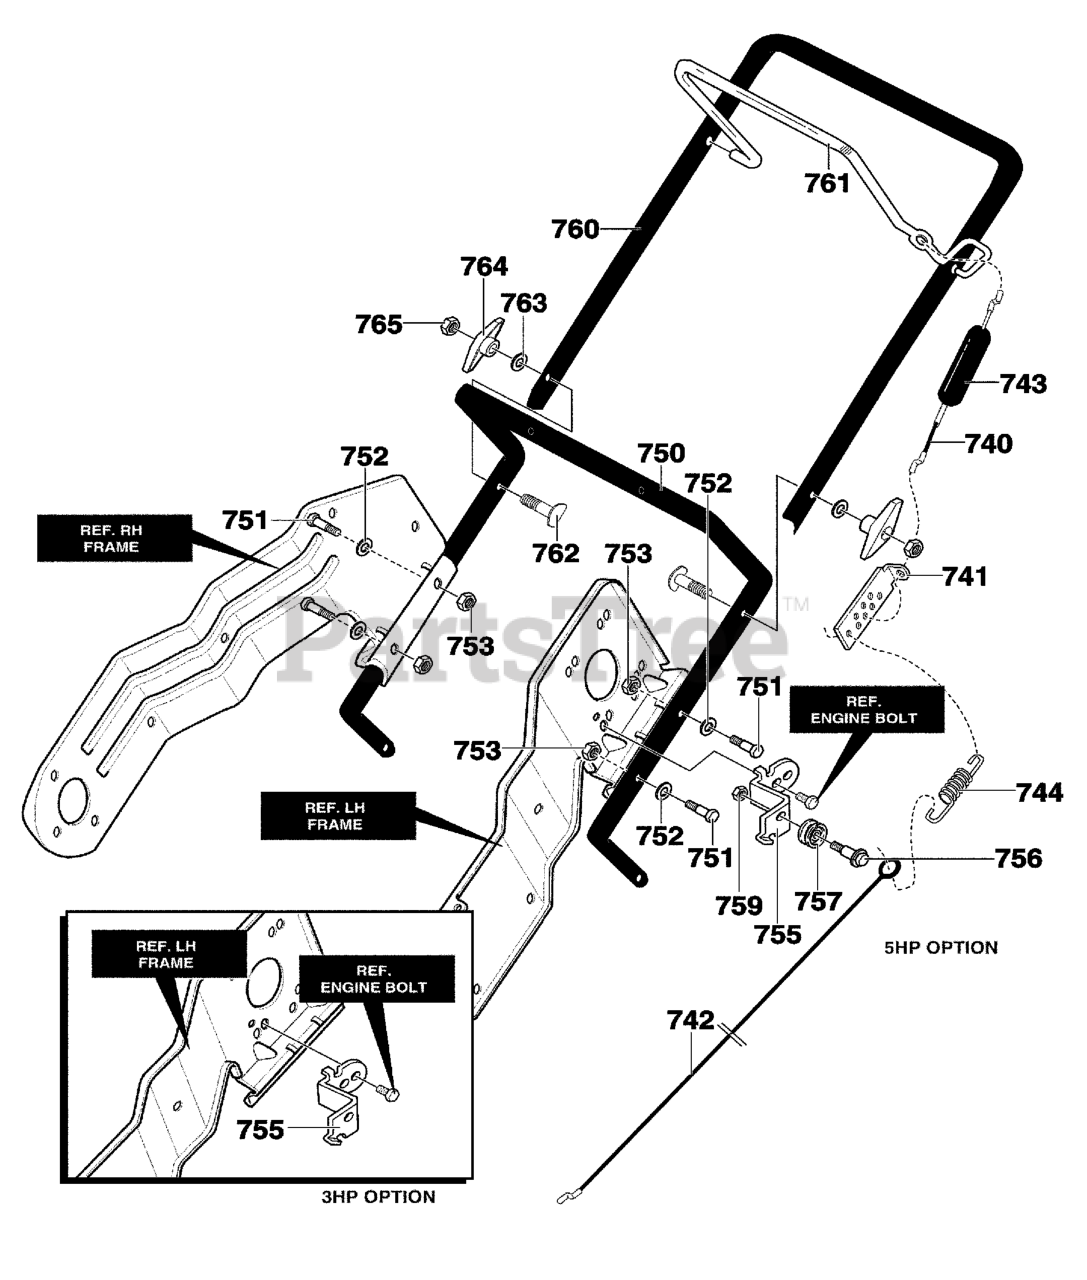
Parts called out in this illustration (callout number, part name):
740	CABLE, UPPER
741	BRKT, CABLE ADJ
742	CABLE LOWER CONTROL
743	BOOT, CLUTCH SPRING
750	HANDLE LOWER
751	SCREW, 1/4-20X1.25
752	WASHER, FLAT .281X.63X.065
753	NUT, 1/4-20 REGHEXCTRLK
755	BRACKET, CABLE
756	BOLT, .375X.375 1/4-20
757	PULLEY, .906X.305
759	NUT, 1/4-20 REGHEXCTRLK
760	HANDLE, UPPER
761	BAIL, CONTROL
762	BOLT, 5/16-18X2.00
763	WASHER, FORM
764	KNOB,T
765	NUT, 5/16-18 REGHEX
